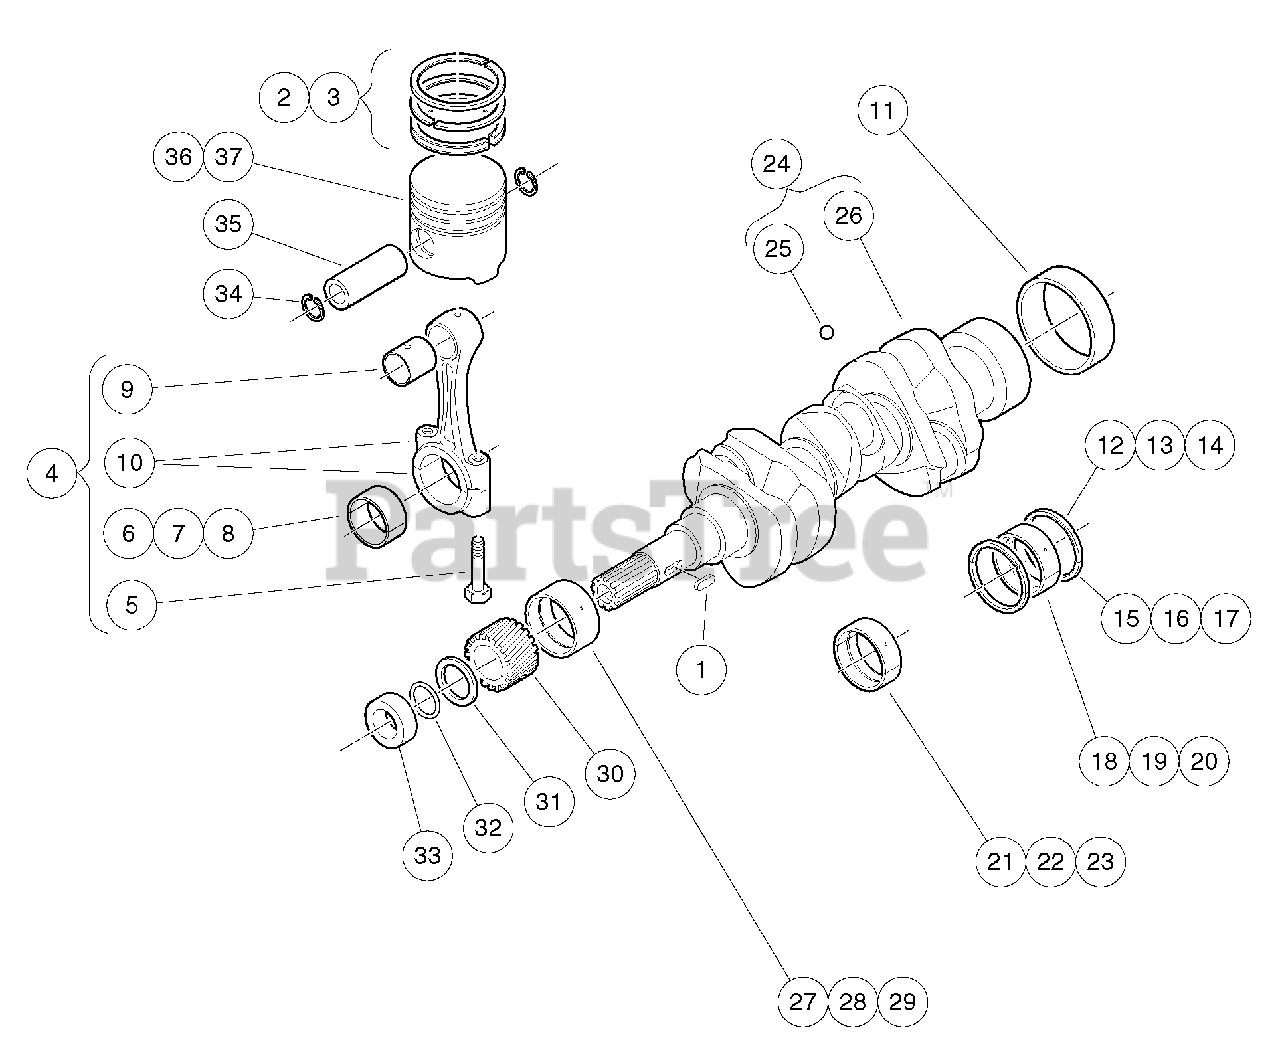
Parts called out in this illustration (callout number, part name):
1	Key, Feather, Short Camshaft
2	Assy Piston Ring, D722 Std
3	Assy Piston Ring, D722 +.025
4	Assy, Connecting Rod
5	Bolt, Connecting Rod
6	Metal, Crank, Rod, D722, Std
7	Metal, Crank, Rod, D722, .020
8	Metal, Crank, Rod, D722, .040
9	Bushing, Piston Pin, D722
10	Rod, Connecting
11	Sleeve, Crankshaft
12	Metal,crank, O Side, Std
13	Metal,crank, O Side, +.020
14	Metal,crank, O Side, +.040
15	Metal,crank, I Side, Std
16	Metal,crank, I Side, +.020
17	Metal,crank, I Side, +.040
18	Metal, Crank, Main, Rear Std
19	Metal, Crank, Main, Rear -.020
20	Metal, Crank, Main, Rear -.040
21	Metal, Crank, Main, Mid Std
22	Metal, Crank, Main, Mid +.020
23	Metal, Crank, Main, Mid +.040
24	Crankshaft
25	Ball, Crankshaft
26	Crankshaft
27	Metal, Crank, D722, Frnt, Std
28	Metal, Crank, 722, Frnt, -.020
29	Metal, Crank, 722, Frnt, -.040
30	Gear, Crank
31	Slinger, Oil
32	O Ring, 23 X 26
33	Collar, Crankshaft
34	Circlip, Piston Pin
35	Pin, Piston
36	Piston, D722, Std
37	Piston, D722, +0.25
